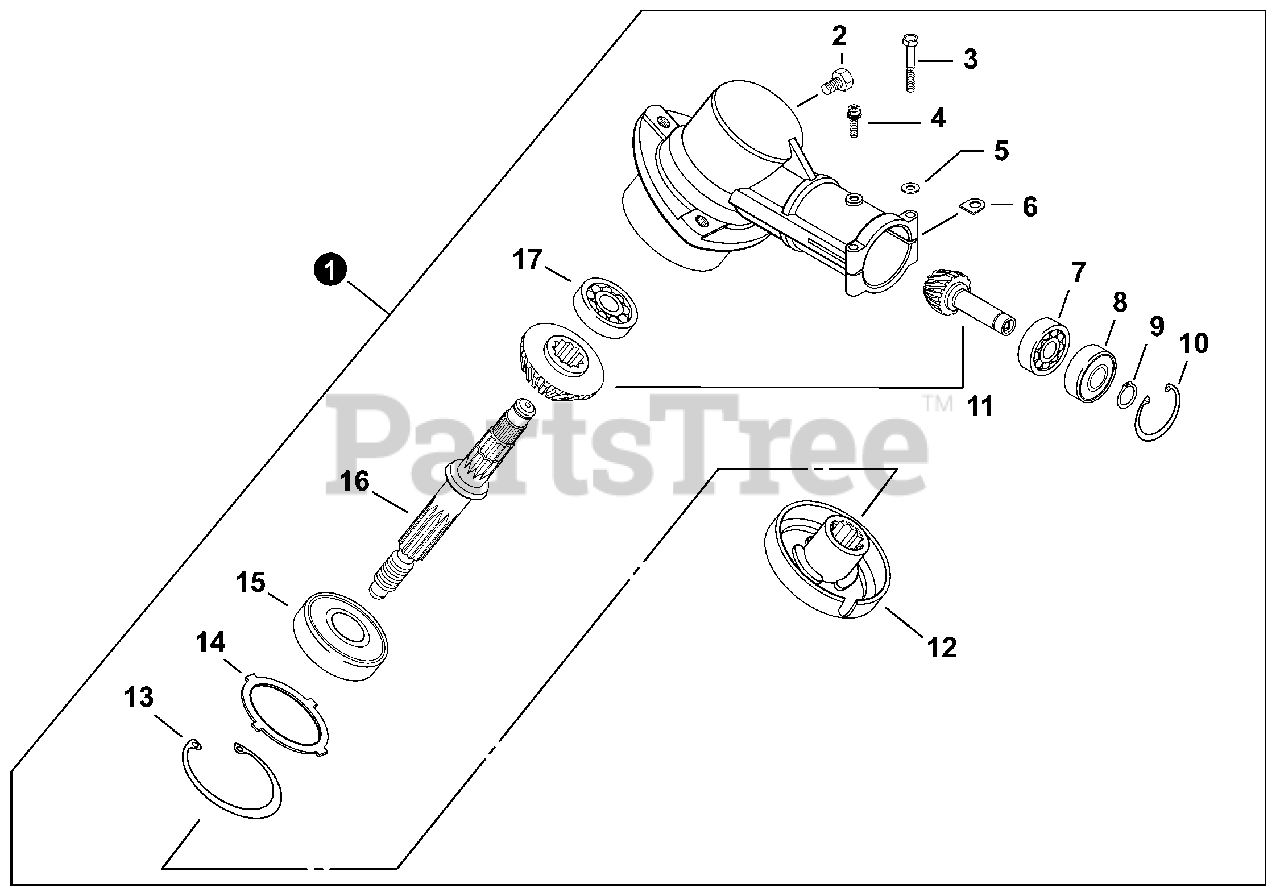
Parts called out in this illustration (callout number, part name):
1	GEAR CASE ASSY
2	BOLT M8x8
3	BOLT 5x35 SP
4	SCREW 5x10
5	WASHER, FLAT 5.5x10x0.8
6	D-WASHER
7	BEARING, BALL 6900
8	BEARING, BALL 6900Z
9	RING, SNAP 10
10	RING, SNAP 22
11	GEAR SET
12	PLATE, ADAPTOR - UPPER
13	RING, SNAP 32
15	BEARING, BALL 6201
16	SHAFT, GEAR
17	BEARING, BALL 609
